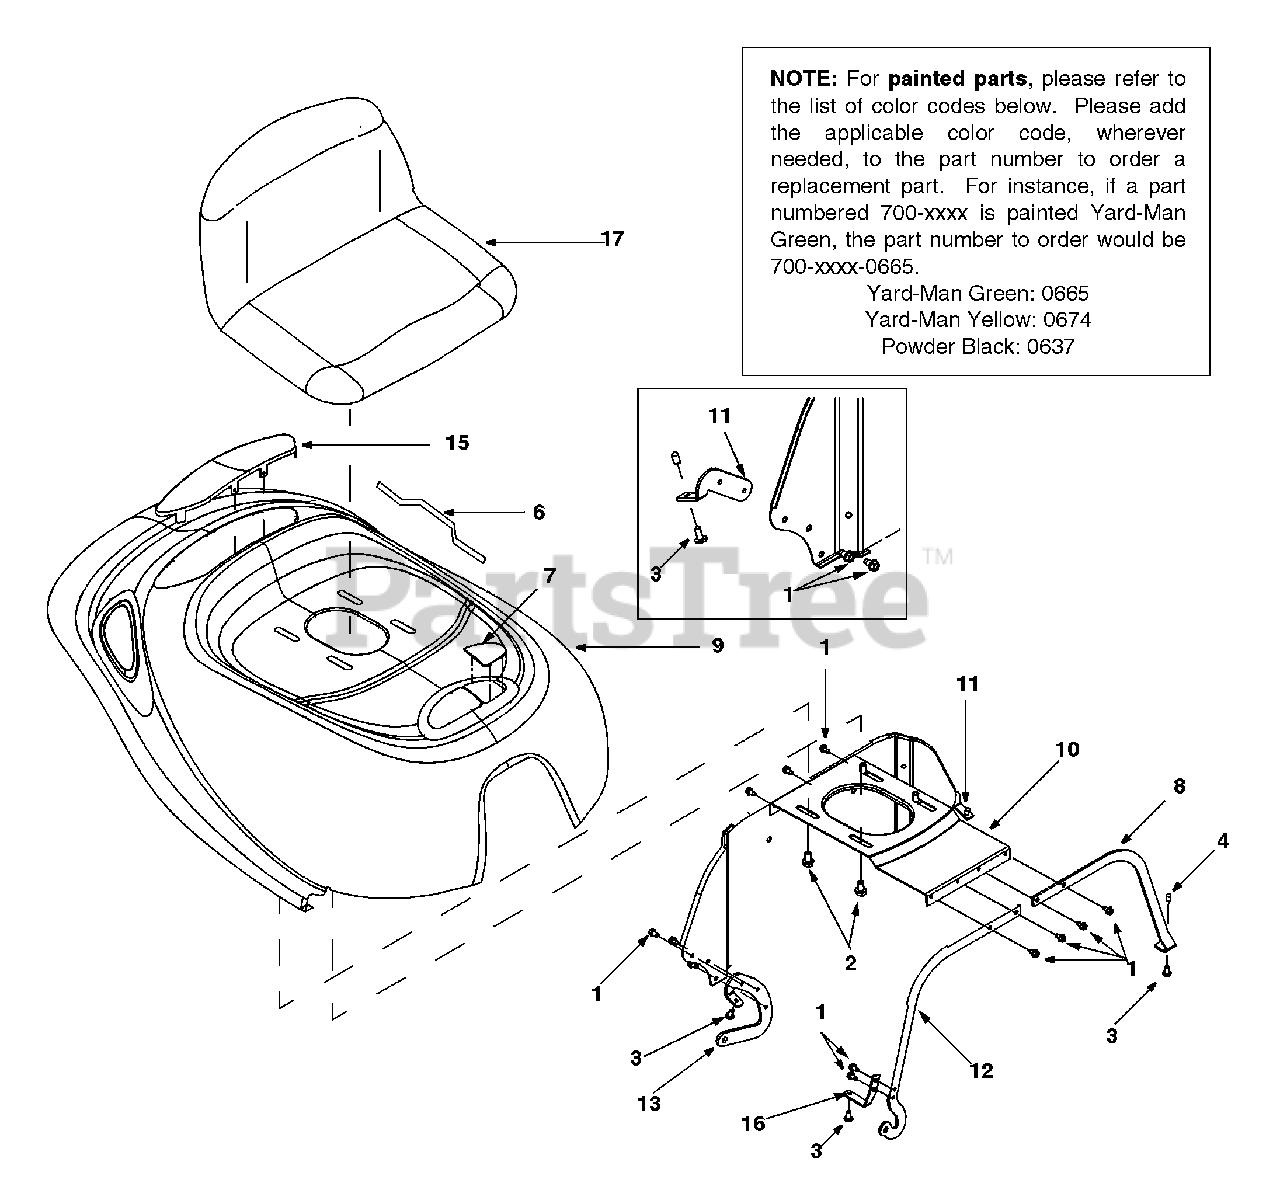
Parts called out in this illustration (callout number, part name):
1	TT Screw 1/4-20 x 0.5
2	TT Screw 3/8-16 x 0.62
3	Torx AB Screw 1/4-14 x 0.625
4	Rod End Grip
6	Trim Strip
7	Grass Bag Lens
